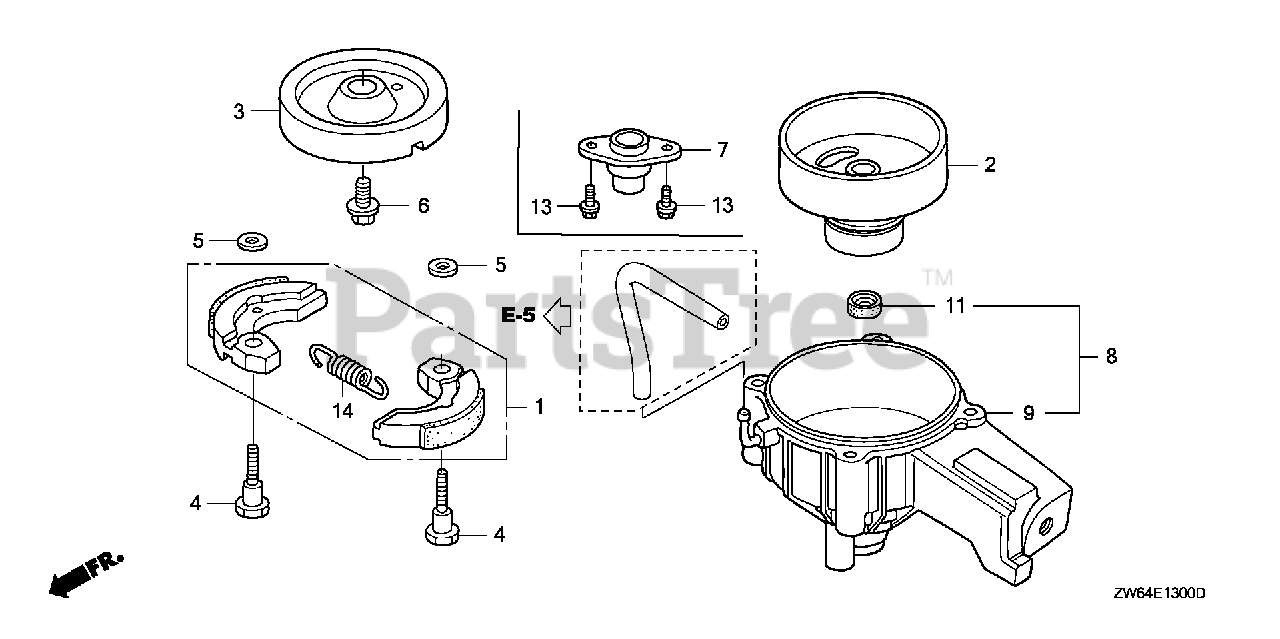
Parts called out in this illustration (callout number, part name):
1	CLUTCH ASSY.
2	CLUTCH OUTER ASSY.
3	STAY, CLUTCH
4	BOLT, CLUTCH (8MM)
5	WASHER, PLAIN (8MM)
6	BOLT, CLUTCH STAY (8MM)
8	HOUSING ASSY., CLUTCH
9	HOUSING, CLUTCH
10	BEARING, RADIAL BALL (6004)
10	BEARING, RADIAL BALL (6004) (NOT AVAILABLE)
11	SEAL, WATER (11X21X8)
12	CIRCLIP (INNER) (42MM)
14	SPRING, CLUTCH SHOE
